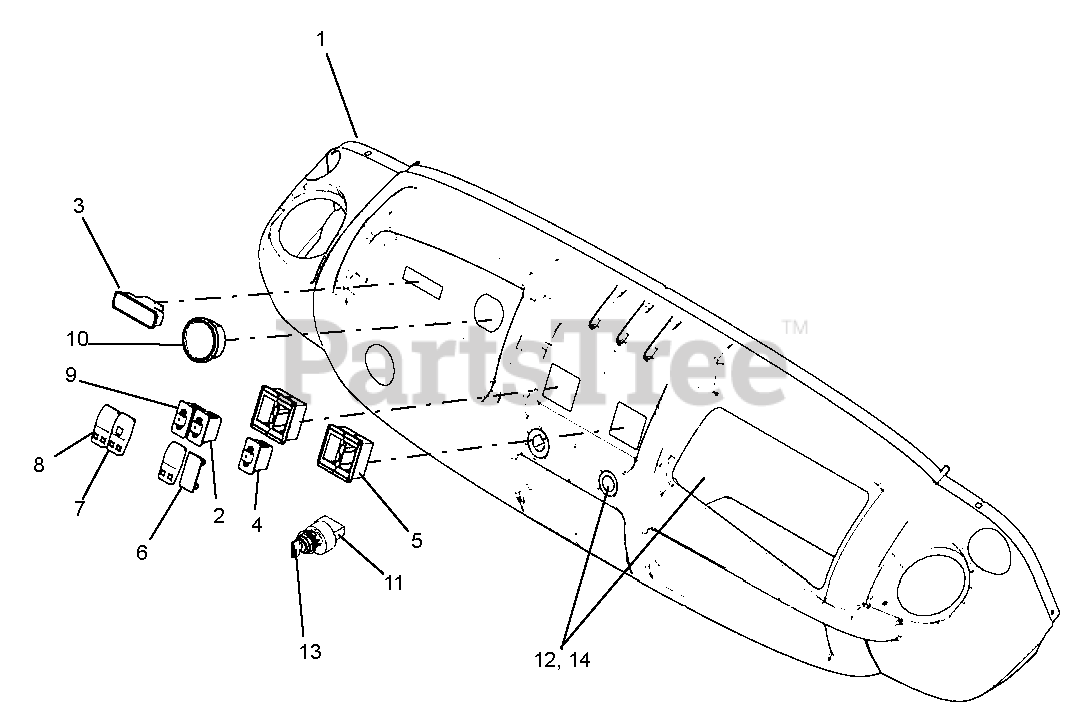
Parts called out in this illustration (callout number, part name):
1	DASH PANEL
2	SWITCH, 4 X 4, LIGHTED (996146, 147)
3	INDICATOR LAMP, 6 LENS
4	DUMP SWITCH WAYTEK 44304
5	SWITCH MOUNT END
6	PANEL PLUG
7	ACTUATOR SWITCH, 4 X 4 (996146, 147)
8	SWITCH, ACTUATOR
9	SWITCH, HEADLIGHT
10	FUEL GAGE, HOUR METER
11	IGNITION SWITCH WITH 2 KEYS (6PIN)
12	POWER OUTLET, 12 VOLT
13	KEY WITH SHIELD (RP FOR T833-336C)
14	CAP, 12V OUTLET
